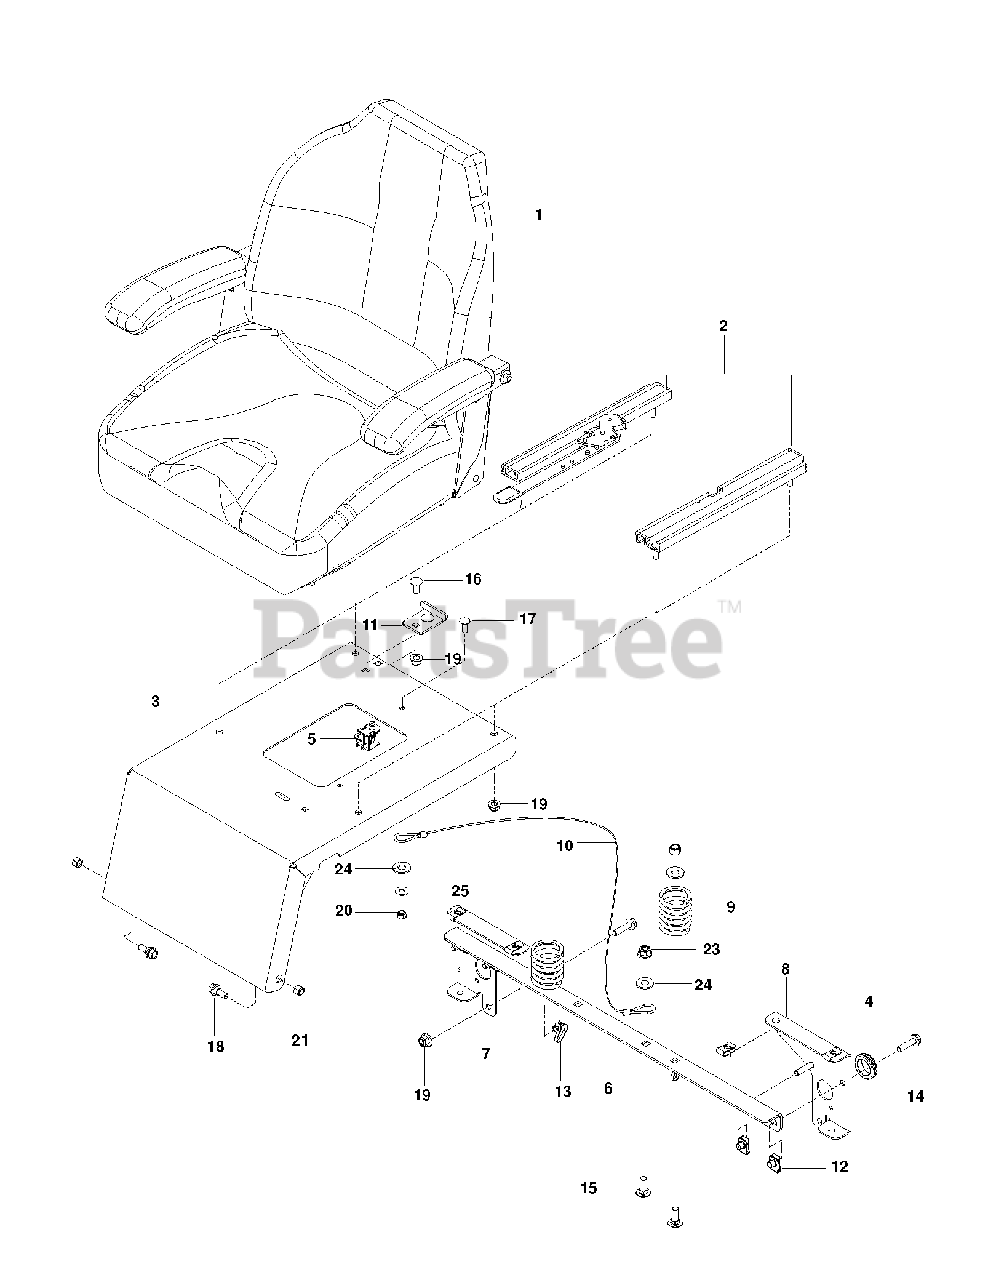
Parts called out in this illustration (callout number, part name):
2	TRACK ADJUSTMENT KIT
4	RUBBER GROMMET
5	SWITCH.SNAPMOUNT.NC
6	SUPPORT, SEAT
7	SUPPORT.RT.BLK
8	SUPPORT.LT.BLK
9	SPRING, SEAT
10	SEAT LANYARD
11	STOP, SEAT - BLACK
12	U-CLIP 5/16-18 NUT RETAINER
13	TIE WRAP, 8-3/8", W/CLIP
14	HHFS 5/16-18 X 1.25 TPBLT GD 5
15	RHSNB 3/8C X 1
16	RHSNB 5/16-18 X 3/4
17	RHSNB 1/4C X 3/4
18	SB 5/16-18 HEX HD GD5, BLK ZN
19	5/16-18 NYLOC FLANGE NUT
20	NUT 1/4-20 NYLOC
21	NUT 5/16 NYLOC
22	NUT 3/8-16 NYLOC
23	NUT 3/8-16 HEX FLG NYLOC ZD
24	WASHER 3/8 FLAT
25	WASHER 1/4 FLAT
